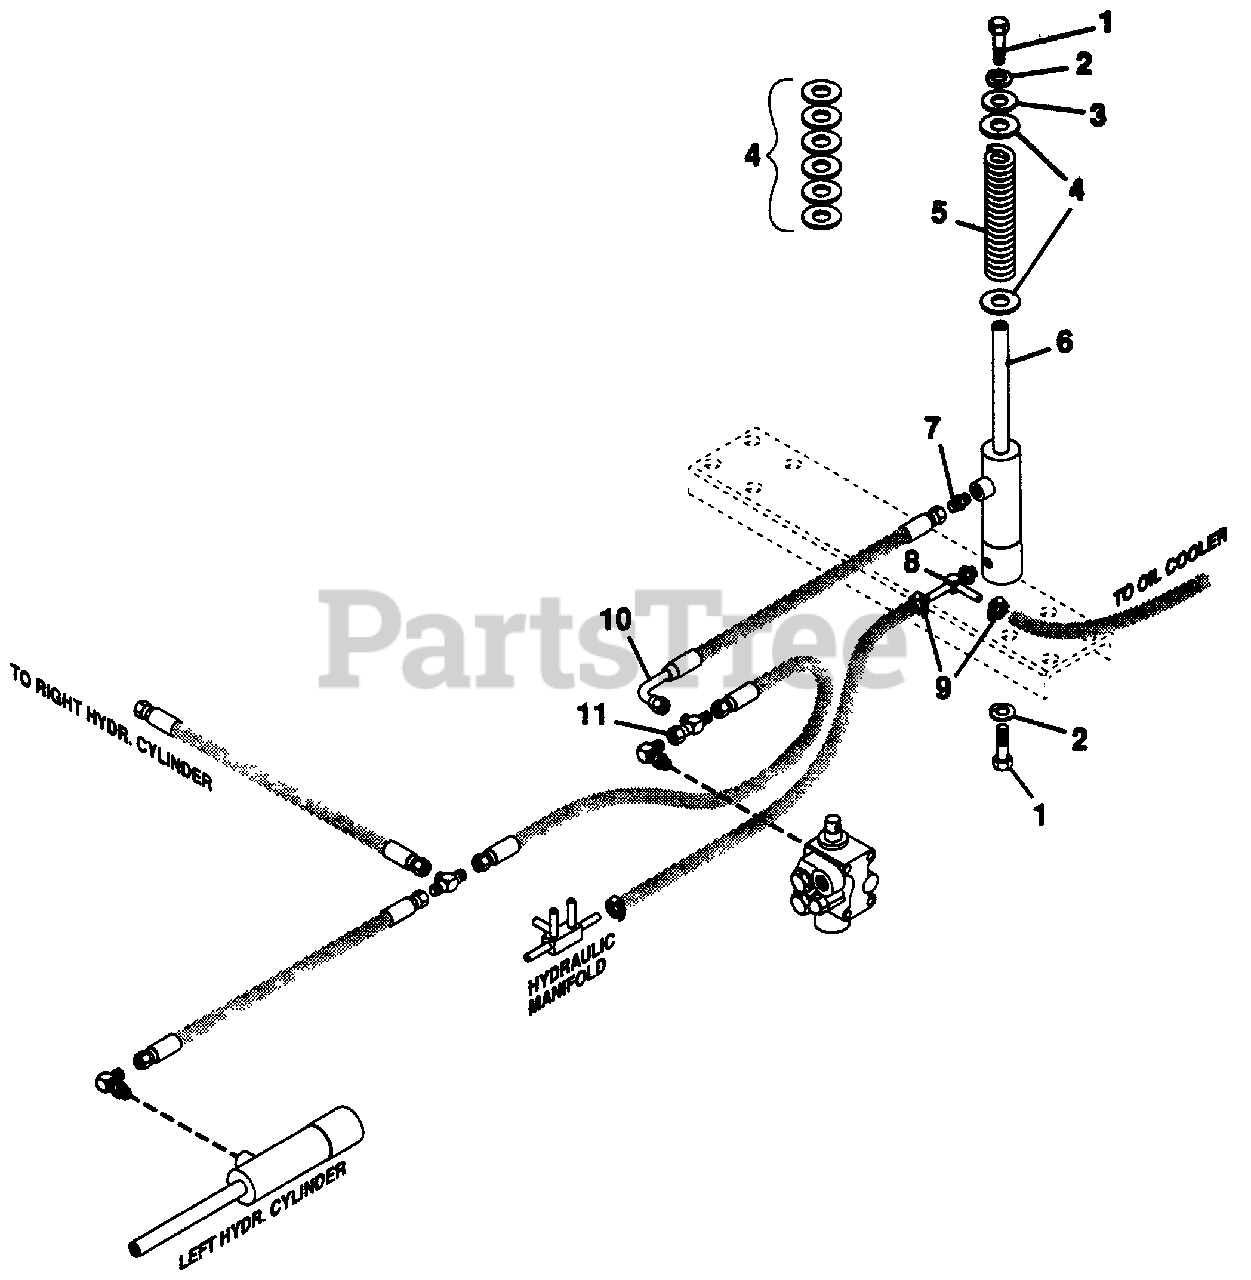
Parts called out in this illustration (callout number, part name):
1	Bolt, Hex 1/2-20x1.00 Gr. 8
2	Washer, Lock 1/2 Reg.
3	Washer, Flat .531x1.250x.100
4	Washer, Flat .812x1.469x.130
5	Spring, Lift Assist
6	Cylinder, Lift Assist
7	Adapter, P.H. #0503-6-6
8	Adapter, 3/8" Barbed Tee
9	Clamp, Hose
10	Hose
11	Adapter, #6602-6-6-6
